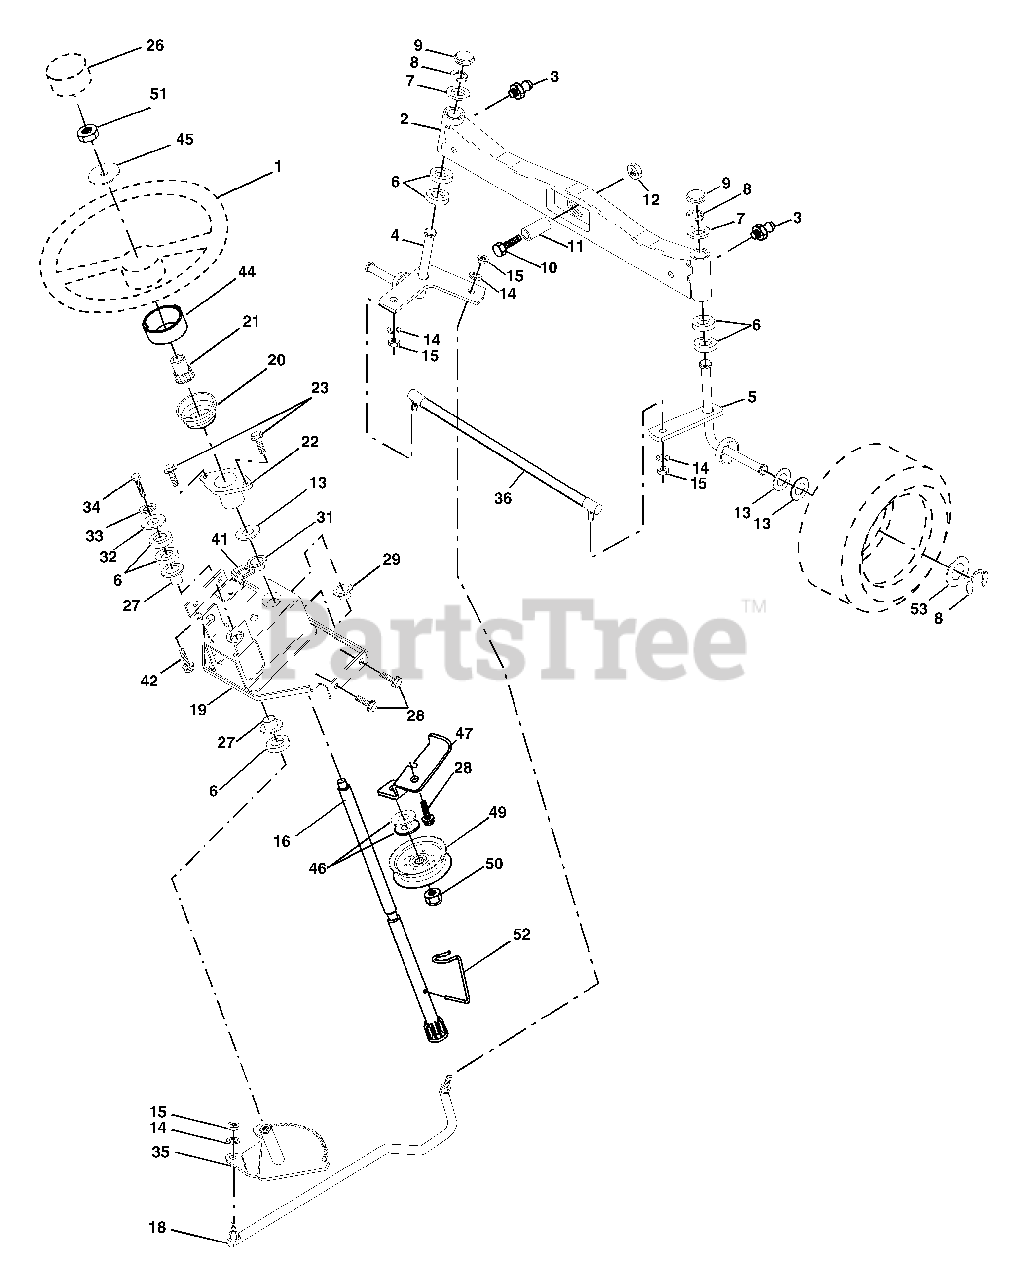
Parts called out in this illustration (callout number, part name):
1	Wheel, Steering
2	Axle Asm., Front
3	Fitting, Grease
4	Spindle Asm, LH
5	Spindle Asm., RH
6	Bearing, Race Thrust Harden
7	Washer 25/32 x 1-5/8 x 16 Ga.
8	Ring, Klip #T5304-75
9	Cap, Spindle
10	Bolt, Fin Hex 5/8-11 x 2-3/4
11	Spacer Brg Axle Front 1.570
12	Nut, Lock Flange 5/8-11 unc
13	Washer 25/32 x 1-1/4 x 16 Ga.
14	Washer, Lock Hvy Hlcl Spr 3/8
15	Nut Crownlock 3/8-24
16	Shaft Asm., Steering
18	Draglink, Ball Joint Solid Vgt
19	Support Asm., Steering Vgt
20	Boot Steering
21	Adapter, Wheel Steering
22	Bushing, Strg.
26	Cap , Wheel Steering
27	Bearing, Col. Strg.
28	Screw 3/8-16 x 3/4
29	Bearing, Flange
31	Bushing, Nyliner Snap
32	Washer 11/32 x 1 x 10 Ga.
33	Washer, Lock Hvy Hlcl Spr 5/16
34	Bolt, Hex Hd 5/16-18 x 3/4
35	Gear, Sector Steering
41	Bracket Switch Inerlock VGT97
42	Screw 5/16-18 x 1/2
44	Extension Steering Premium
45	Washer 9/16 ID x 1 1/2 OD 11 Ga. Zin
46	Washer 13/32 x 1 x 10 Ga.
47	Bracket Asm. Idler
49	Pulley Idler Flat
50	Nut Lock Flg 3/8-16 unc
51	Nut Hex Jam Toplock 1/2-20 unf
52	Clip Steering .750
53	Washer Harden .793 x 1.63 x 060
